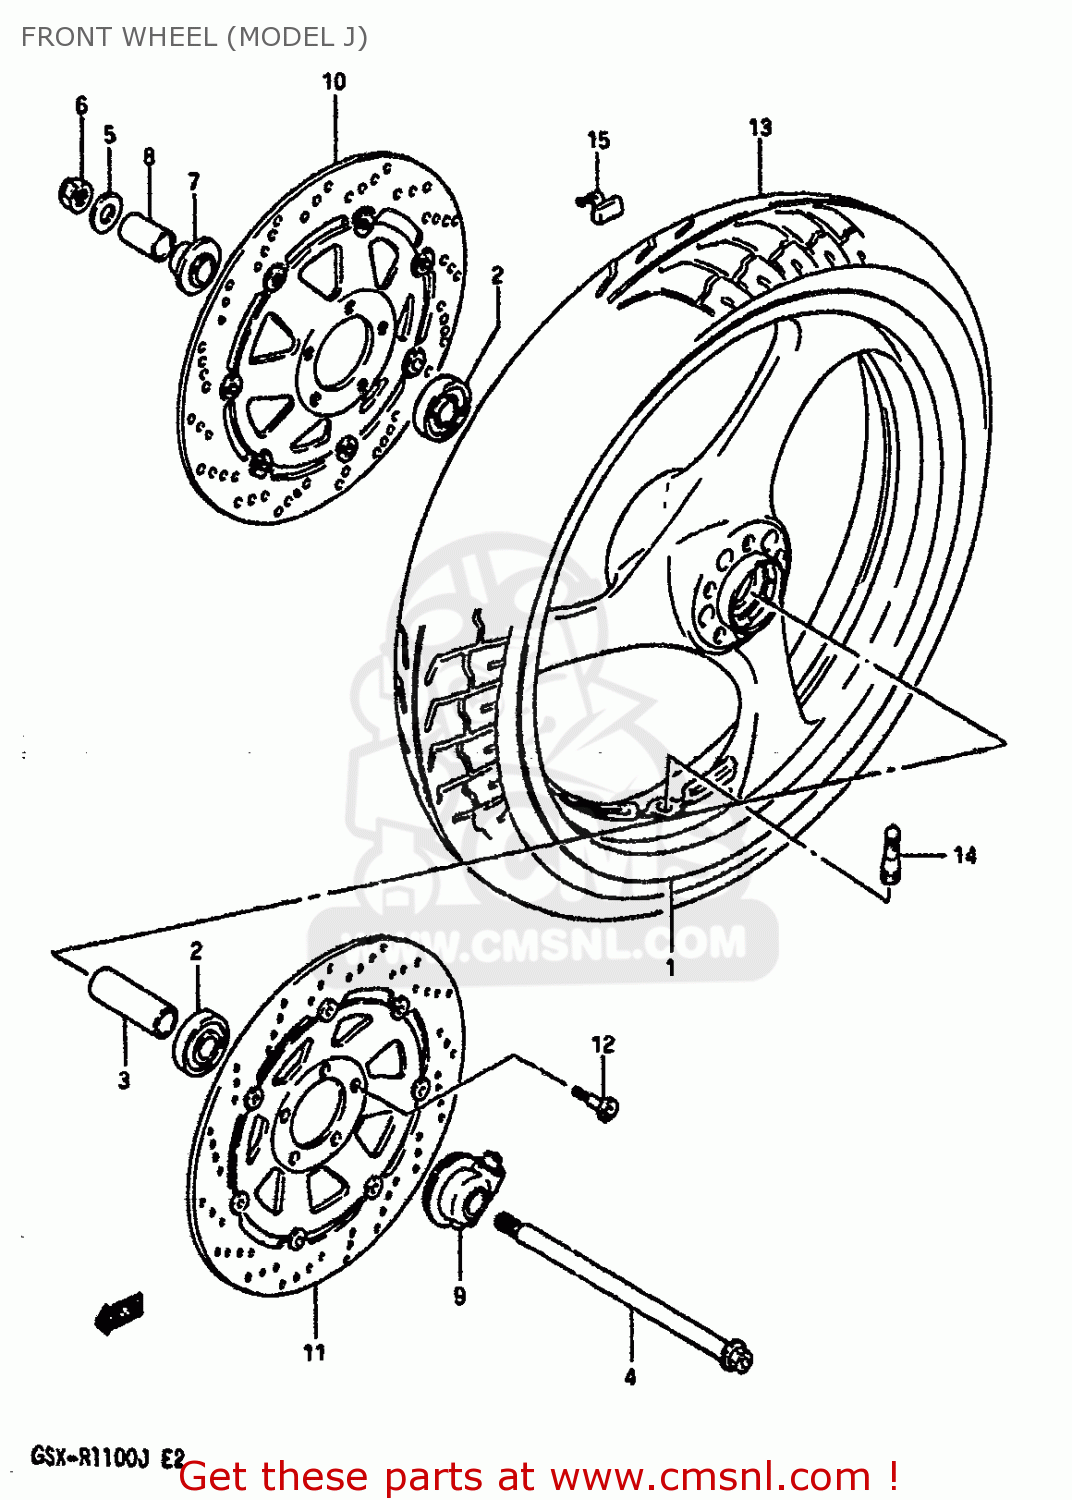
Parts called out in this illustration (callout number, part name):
1	WHEEL,FRONT (18XMT2.75)
2	BEARING
3	SPACER (17.3X24X76)
4	AXLE,FR
5	WASHER
6	NUT
7	SPACER COMP,FRONT HUB
8	SPACER,FR AXLE
9	BOX ASSEMBLY,SPEEDOMETER GEAR
10	DISC,FR BRAKE,R
11	DISC,FR BRAKE,L
12	BOLT
13	TIRE,TUBELESS 110/80V
14	VALVE,TIRE
15	BALANCER,WHEEL
